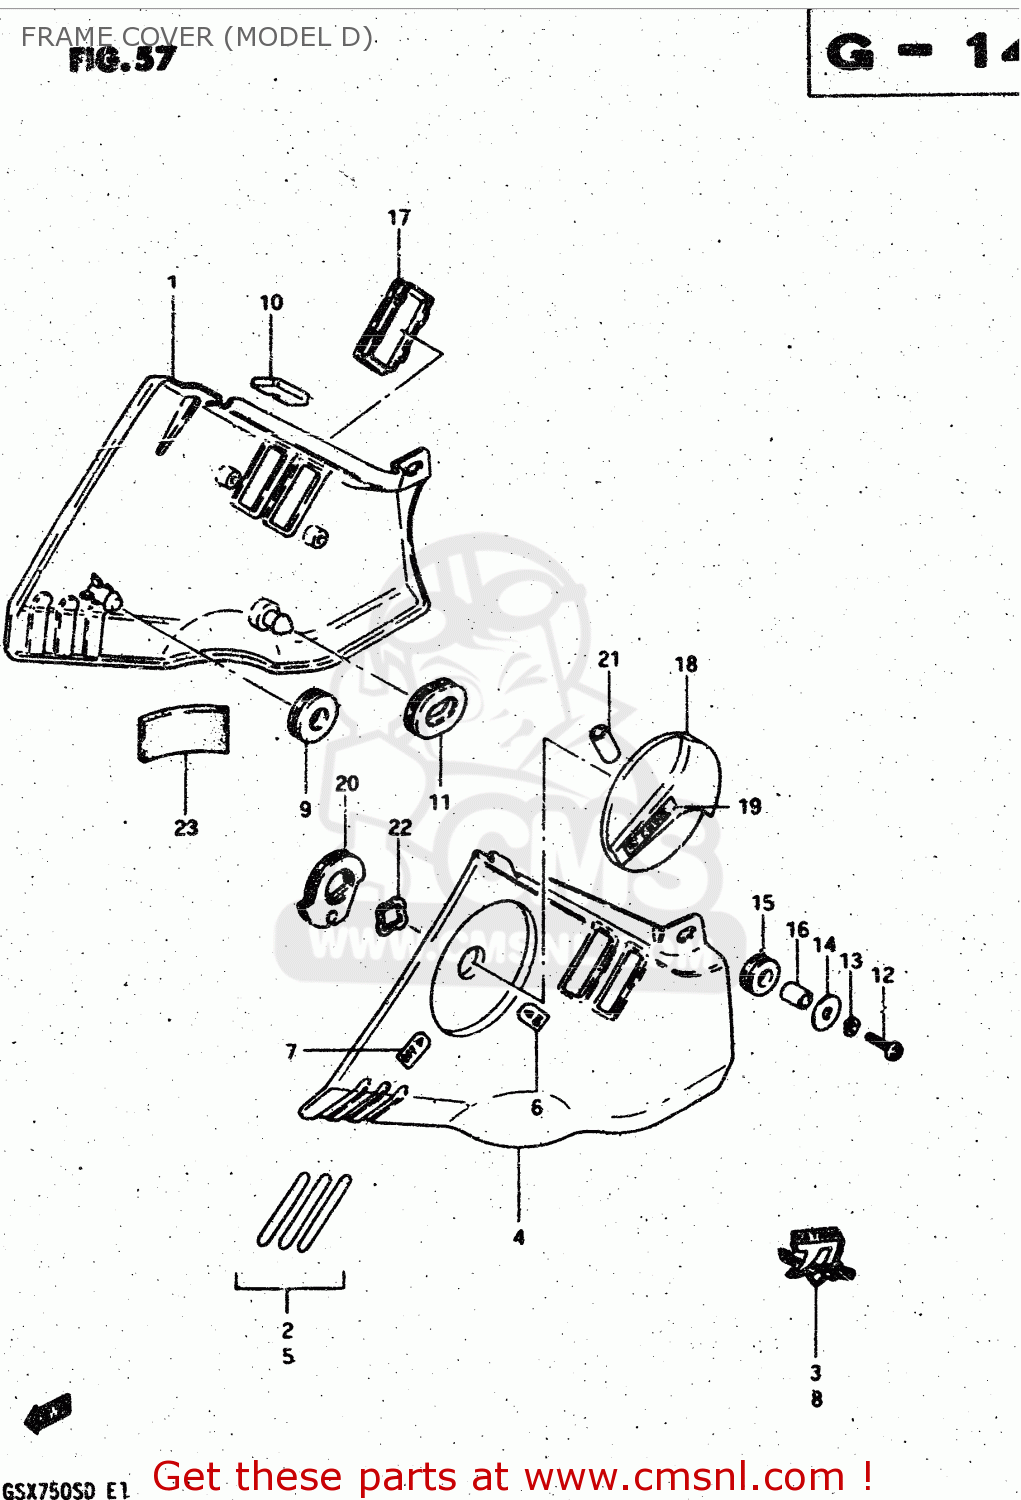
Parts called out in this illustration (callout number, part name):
1	COVER SET,FRAME,R(SILVER)
2	LABEL,FRAME COVER DENT
3	EMBLEM (KATANA)
4	COVER SET,FRAME,L(SILVER)
5	LABEL,FRAME COVER
6	LABEL,CHOKE ON
7	LABEL,CHOKE OFF
8	EMBLEM (KATANA)
9	CUSHION
10	CUSHION
11	CUSHION
12	SCREW
13	LOCK WASHER
14	WASHER
15	CUSHION
16	SPACER(6.1X9X7.5)
17	CAP,FRAME COVER SWITCH HOLE
18	LEVER,CHOKE CABLE
19	LABEL,CHOKE LEVER
20	HOLDER,STARTER CABLE
21	TUBE,CHOKE CABLE LEVER
22	WASHER
23	PAD
